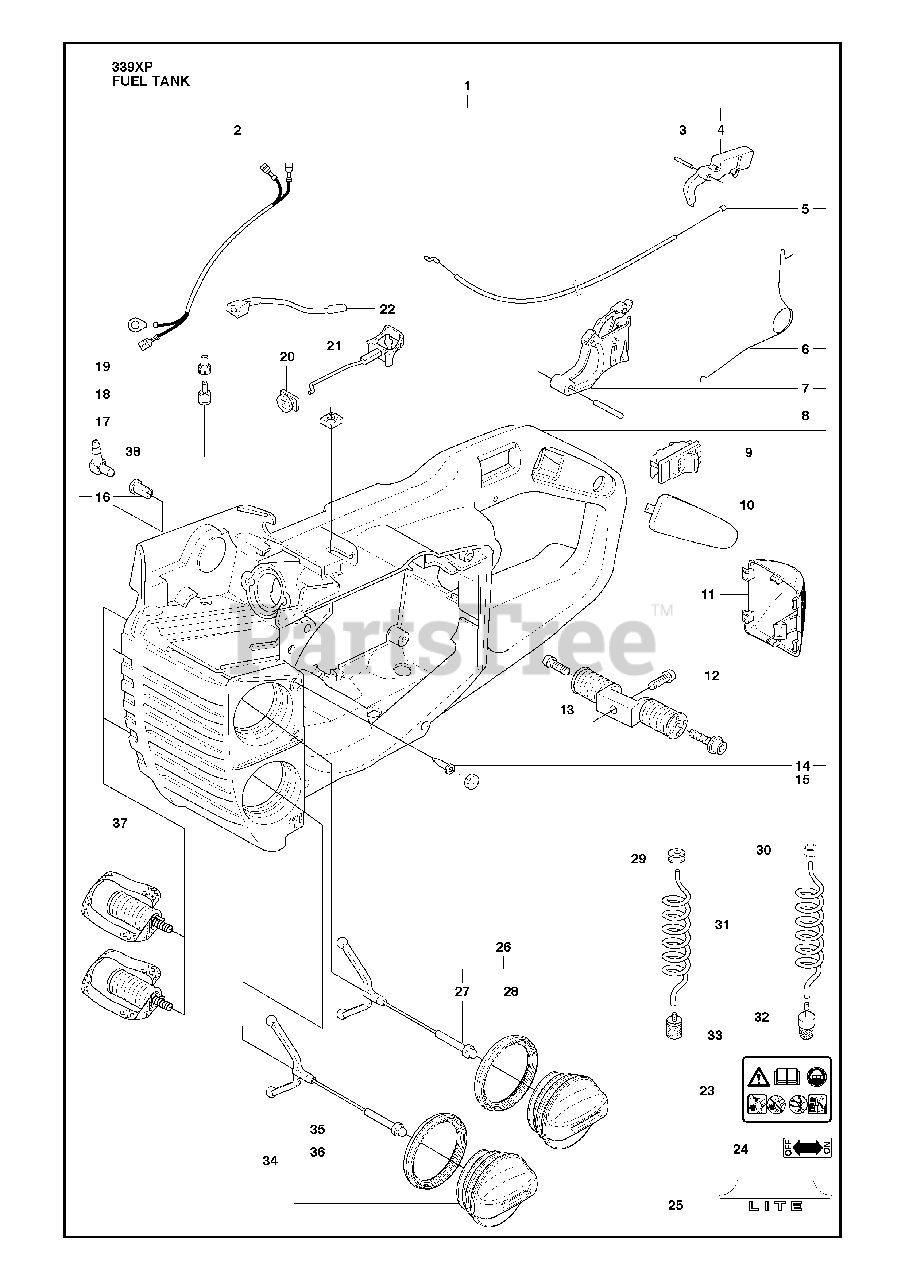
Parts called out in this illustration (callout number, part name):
1	RP TANK
2	CABLE ASSY
3	PIN 3X25
4	THROTTLE CATCH
5	THROTTLE WIRE
7	THROTTLE TRIGGER
9	START/STOP SWITCH
11	SPARK PLUG COVER
13	VIBRATION ABSORBER
14	VALVE-CHECK (DUCKBILL)
18	FUEL TANK VENT
21	CHOKE CONTROL
24	Decal
25	Decal
26	TANK CAP
29	FUEL TANK BUSHING
30	CLAMP
31	FUEL HOSE
32	OIL PLUMMET
33	FUEL FILTER
34	TANK CAP LIGHT GRAY
37	ANTI-VIBE ELEMENT
